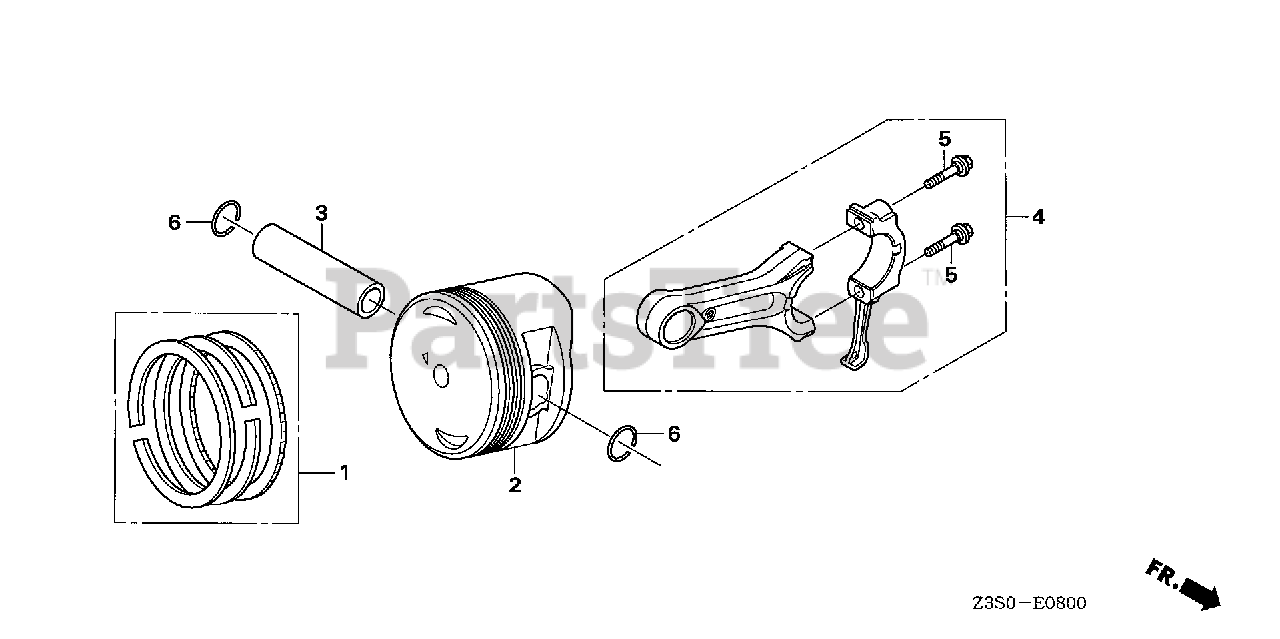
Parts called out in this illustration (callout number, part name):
1	RING SET, PISTON
3	PIN, PISTON
4	ROD ASSY., CONNECTING
5	BOLT, CONNECTING ROD
6	CLIP, PISTON PIN (21MM)
